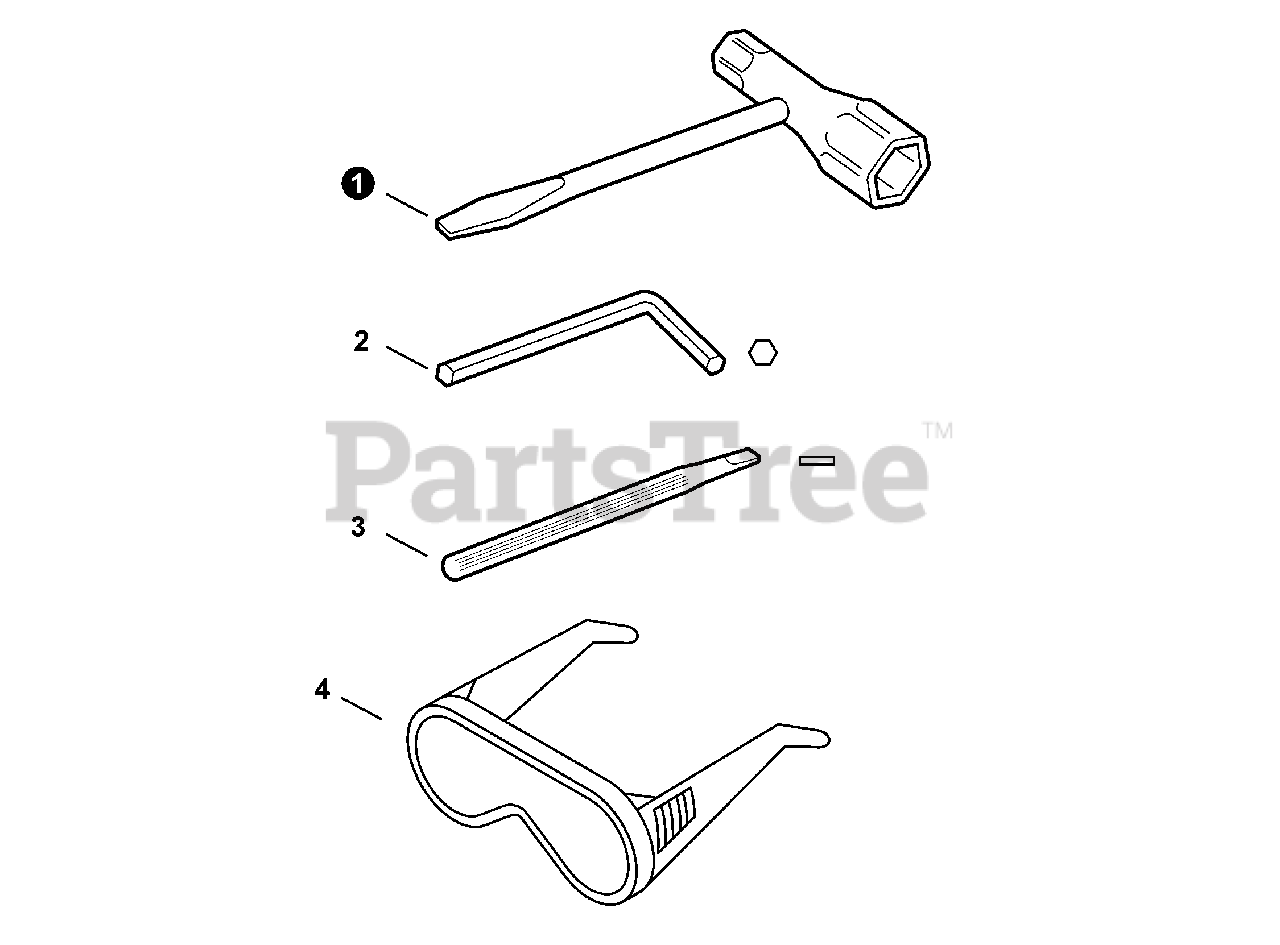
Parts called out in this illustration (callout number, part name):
1	T-WRENCH 13×19 MM
2	WRENCH, ALLEN 4 MM
3	SCREWDRIVER, PLASTIC
4	GLASSES, SAFETY
